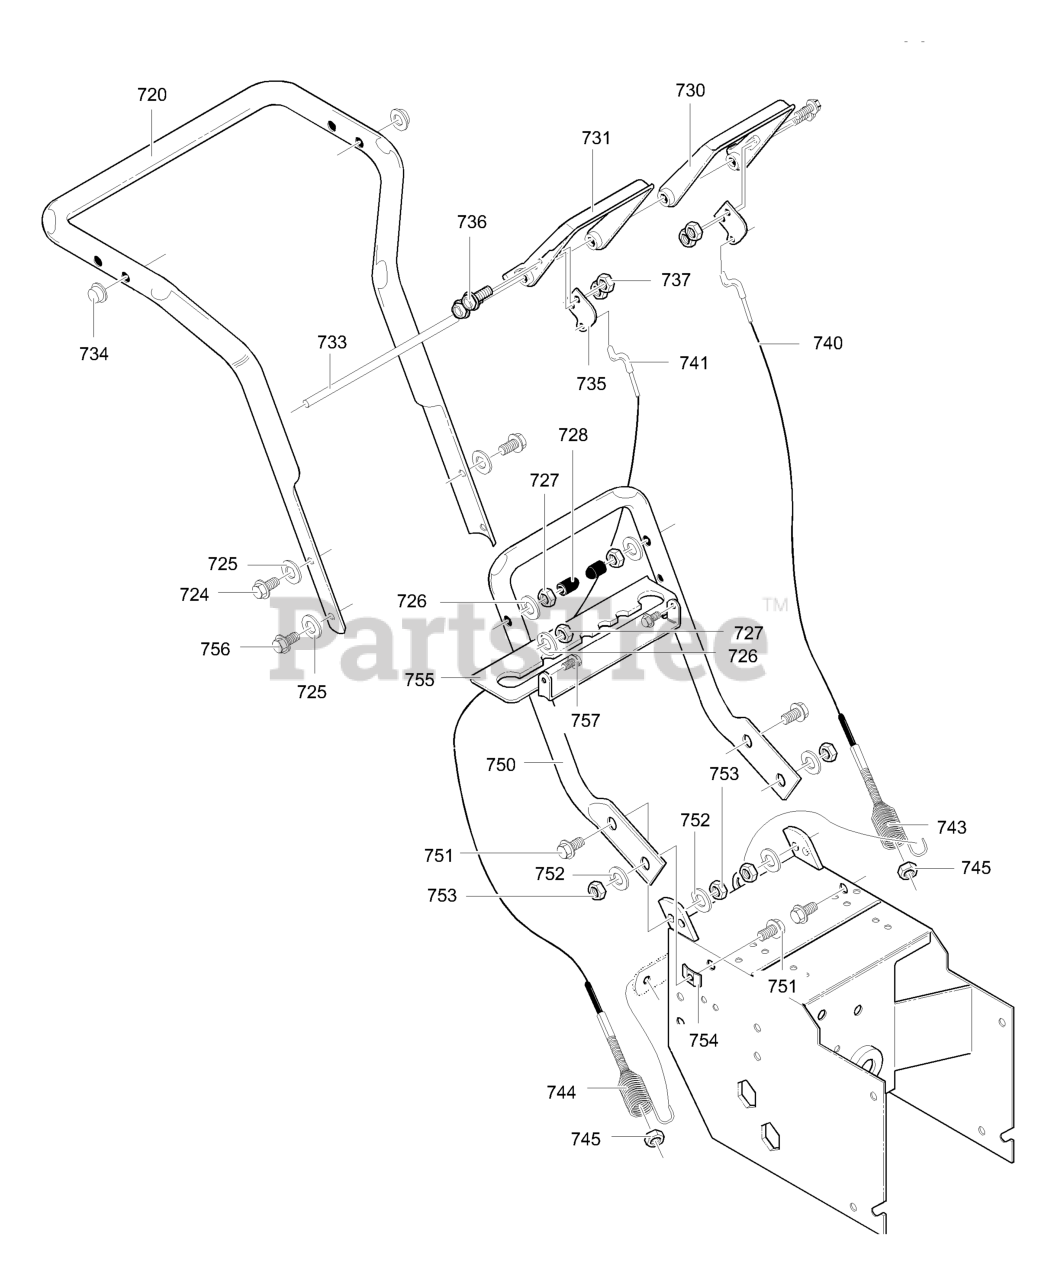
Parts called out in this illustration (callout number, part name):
724	SCREW
725	WASHER, FLAT
726	WASHER
727	NUT
728	PLASTIC-STOP
730	CLUTCH, LEFT HANDLE CONTROL
731	CLUTCH, RIGHT HANDLE CONTROL
733	ROD, PIVOT HANDLE
734	PUSH ON CAP
735	PLATE, CABLE PIVOT
740	CABLE, CLUTCH
741	CABLE, AUGER CLUTCH
743	SPRING, TENSION
744	SPRING, AUGER CLUTCH
745	LOCKNUT
750	HANDLE, LOWER
752	WASHER
753	NUT
755	BRACKET, GEAR SELECTOR
